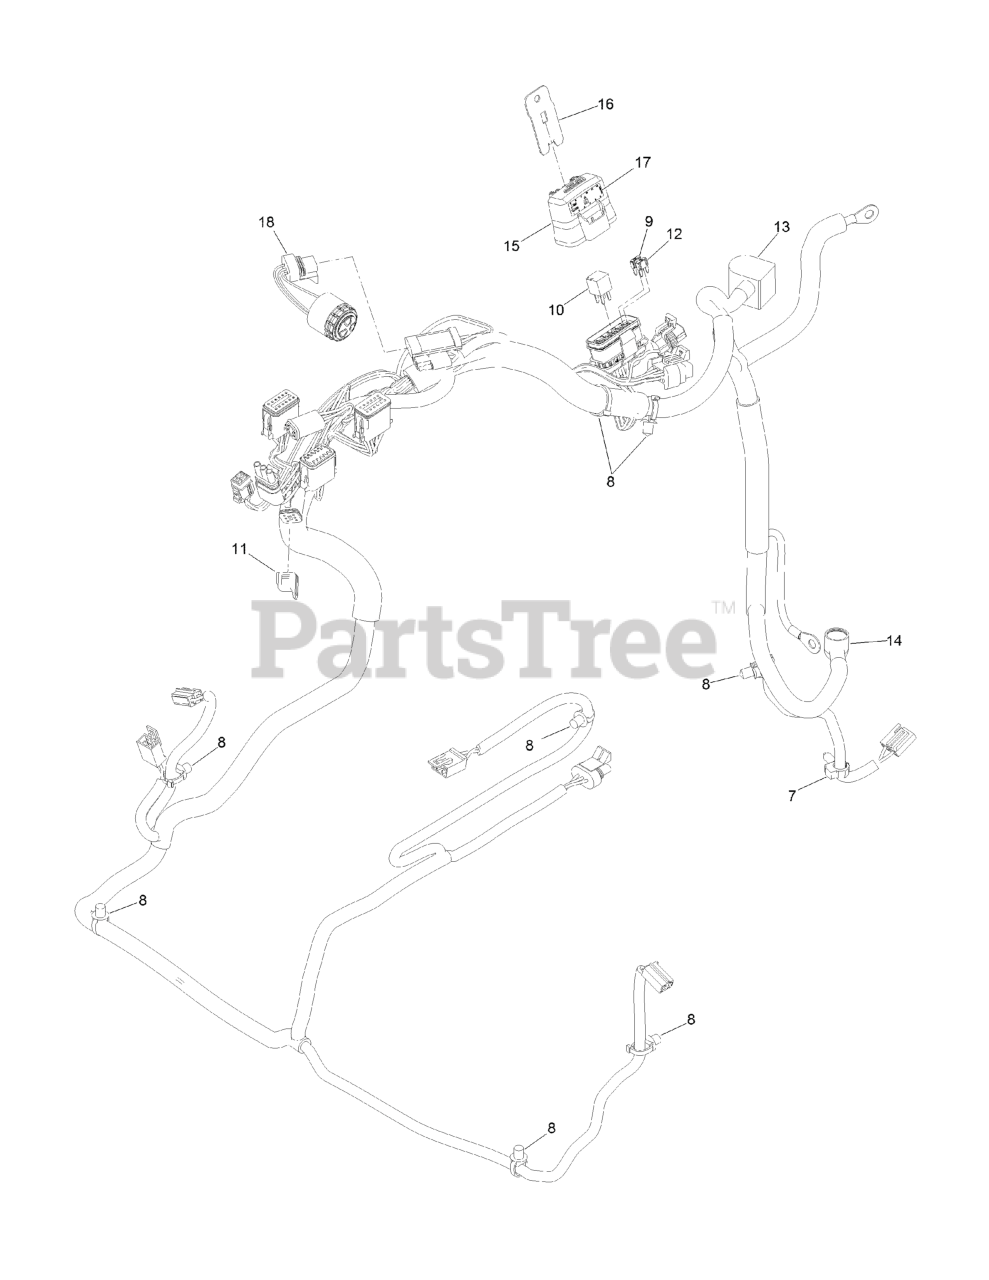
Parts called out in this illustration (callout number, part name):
7	CLIP-HARNESS
8	CLIP-TIE
9	FUSE-MINI BLADE, 20 AMP
10	RELAY-MICRO
11	CAP-PLUG, 6 WAY
12	FUSE-MINI BLADE, 15 AMP
13	INSULATOR-BATTERY
14	INSULATOR-SOLENOID
15	COVER-BLOCK, FUSE
16	CLIP-MOUNTING
17	DECAL-FUSE
18	ALARM-DUAL TONE
